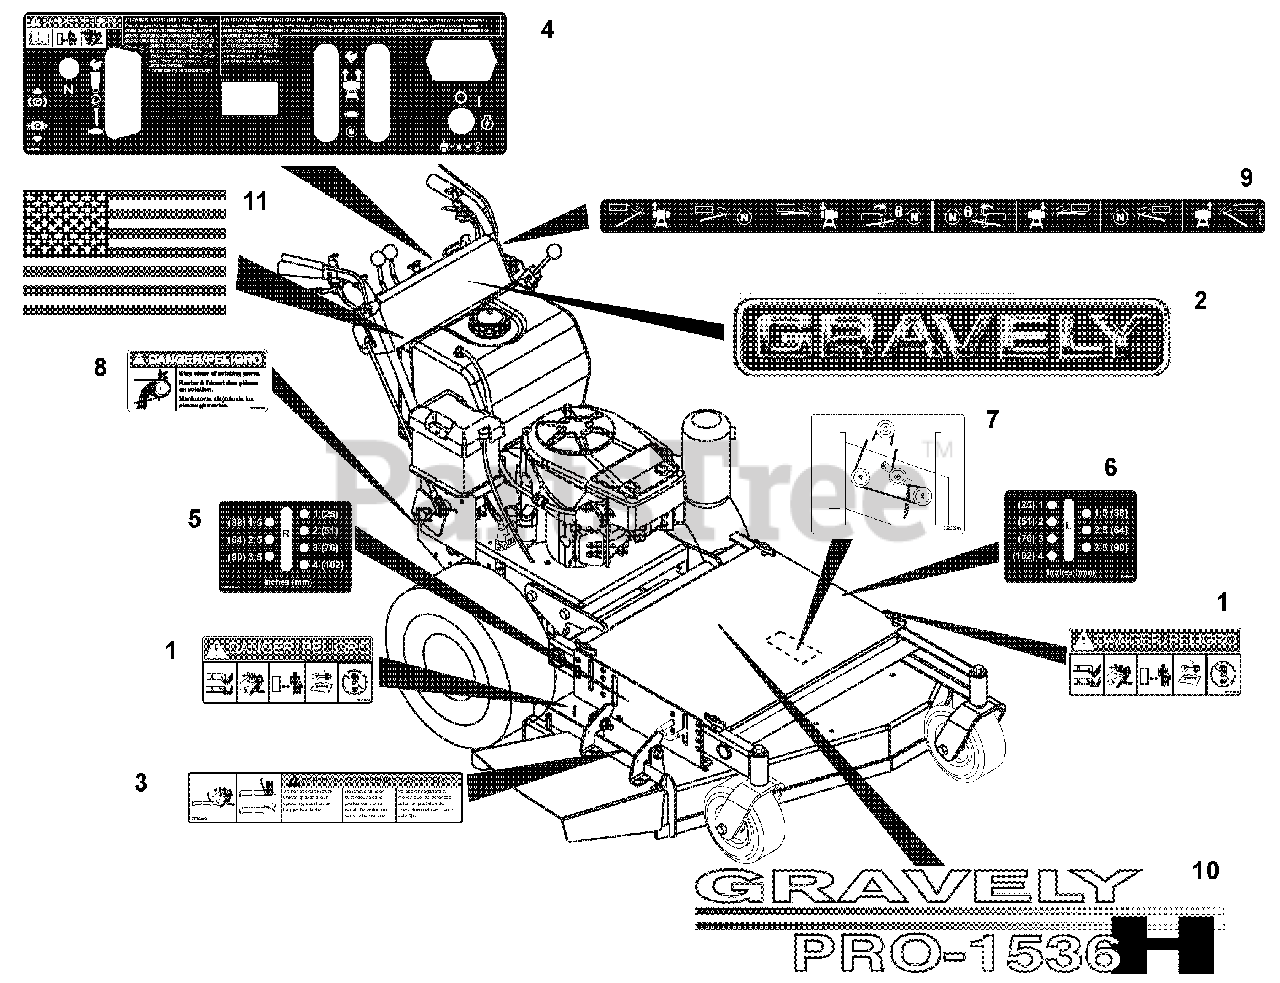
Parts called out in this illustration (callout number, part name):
1	Decal, Mower Pan Head Danger
2	Decal- 15" Gravely Logo
3	Decal, Warning (106, 120)
4	Decal, Control HR15 (106)
5	Decal, Height of Cut-Fixed- Right Hand
6	Decal, Height of Cut-Fixed- Left Hand
7	Decal, Belt Diagram-2 Spindle (120, 314)
8	Decal, Danger-Belt Rotating
9	Decal, Steer Levers (Hydro)
10	Decal, Pro 1536H (120, 314)
11	Decal, American Flag
